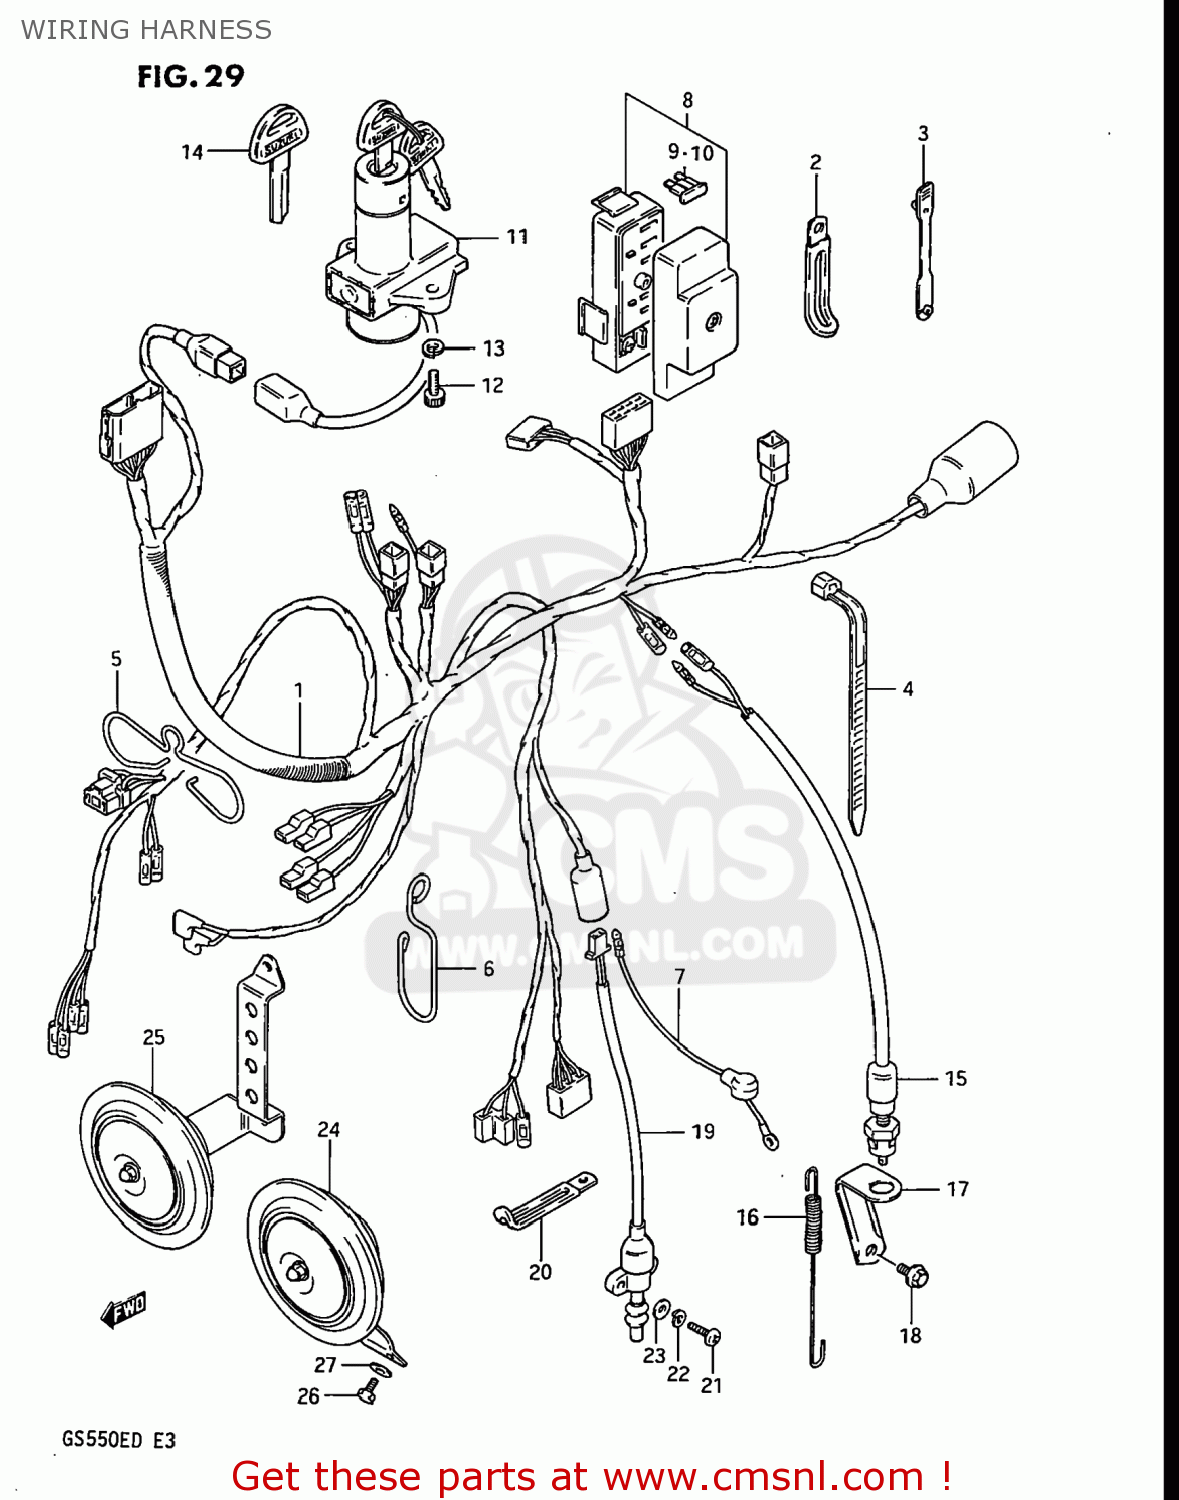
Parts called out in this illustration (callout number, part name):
1	HARNESS,WIRING
2	CLAMP
3	CLAMP,L:88
4	CLAMP(L:95)
5	BOOT,WIRING HARNESS
6	BOOT,WIRING HARNESS
7	WIRE
8	FUSE BOX ASSY
9	FUSE(10A)
10	FUSE(15A)
11	SWITCH ASSY,IGNITION
12	BOLT
13	LOCK WASHER
14	KEY,BLANK
15	SWITCH ASSEMBLY,STOP LAMP
16	SPRING
17	BRACKET,BRAKE LAMP SWITCH
18	BOLT
19	SWITCH ASSEMBLY,SIDE STAND
20	CLAMP
21	SCREW 5X20
22	LOCK WASHER
23	WASHER
24	HORN ASSEMBLY
25	HORN ASSEMBLY
26	BOLT
27	WASHER
